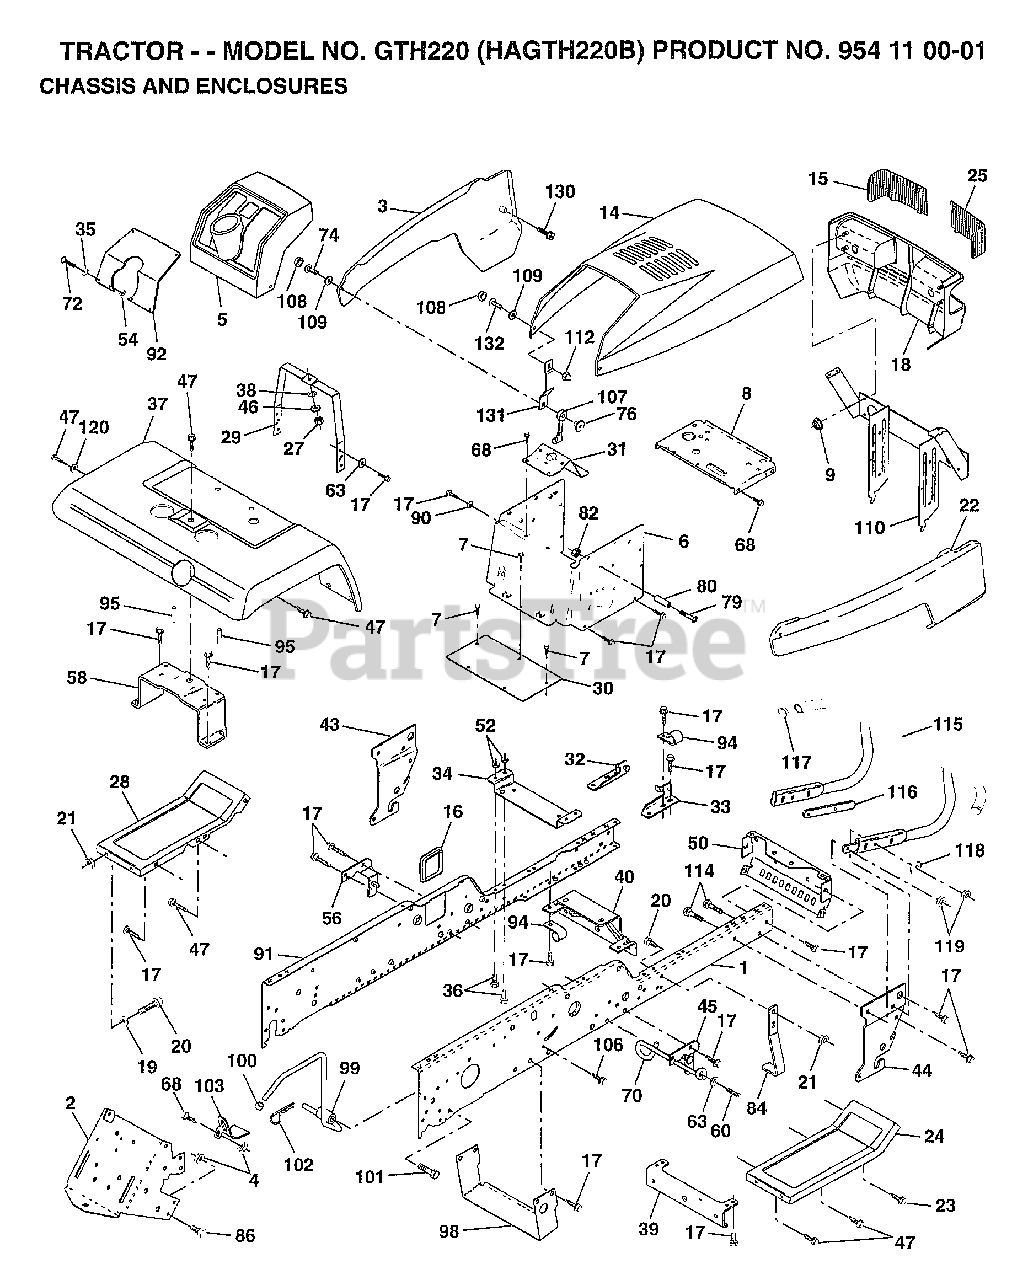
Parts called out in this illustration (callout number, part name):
4	NUT, LOCK HEX 7/16
5	DASHBOARD YP GRAY
7	SCREW, 1/4-20 X 1/2
15	"LENS-HEADLIGHT,LH"
17	SCREW THDROL 3/8-16X3/4 TY-TT
19	WASHER
20	BOLT FIN HEX 3/8-16 X 1
21	NUT, CROWNLOCK 3/8-16
23	SCREW THDROL 3/8-16 X 1 TY-TT
25	"LENS-HEADLIGHT,RH"
27	NUT, HEX 1/4-20
35	WASHER 11/32 X 11/16 X 16 GA.
36	BOLT, FIN HEX 5/16-18 X 3/4
38	WASHER, LOCK 1/4
46	WASHER, 9/32 X 3/4 X 16 GA.
47	SCREW THDROL 3/8-16X1/2 TY-TT
52	LOCKNUT
54	NUT, KEPS 5/16-18
60	SCREW THDROL 3/8-16 X 1-1/4 TYTT
63	WASHER 13/32 X 1 X 14 GA
68	SCREW, 5/16-18 X 1/2 HEX, SELF TAPPING
72	SCREW MACHINE TRHD 5/16-18 X 3/4
74	SCREW, MACHINE #10-24
79	SCREW, MACHINE #10-24 X 1/4
82	NUT, #10-24
86	BOLT, FIN HEX 7/16-14 UNC X 1
90	WASHER LOCK
101	SCREW, THDROL 3/8-16 X 1-3/4
110	PIVOT.ASM.GRL/HD
114	BOLT, CARRIAGE 3/8-16 X 1-1/4
118	WASHER 13/32 X 13/16 X 16 GA
119	NUT, CROWNLOCK 3/8-16
120	WASHER
130	SCREW, SLTD HEX HD W/PL WASHER
132	SCREW, TRUSS HD #10-24 X 3/8
